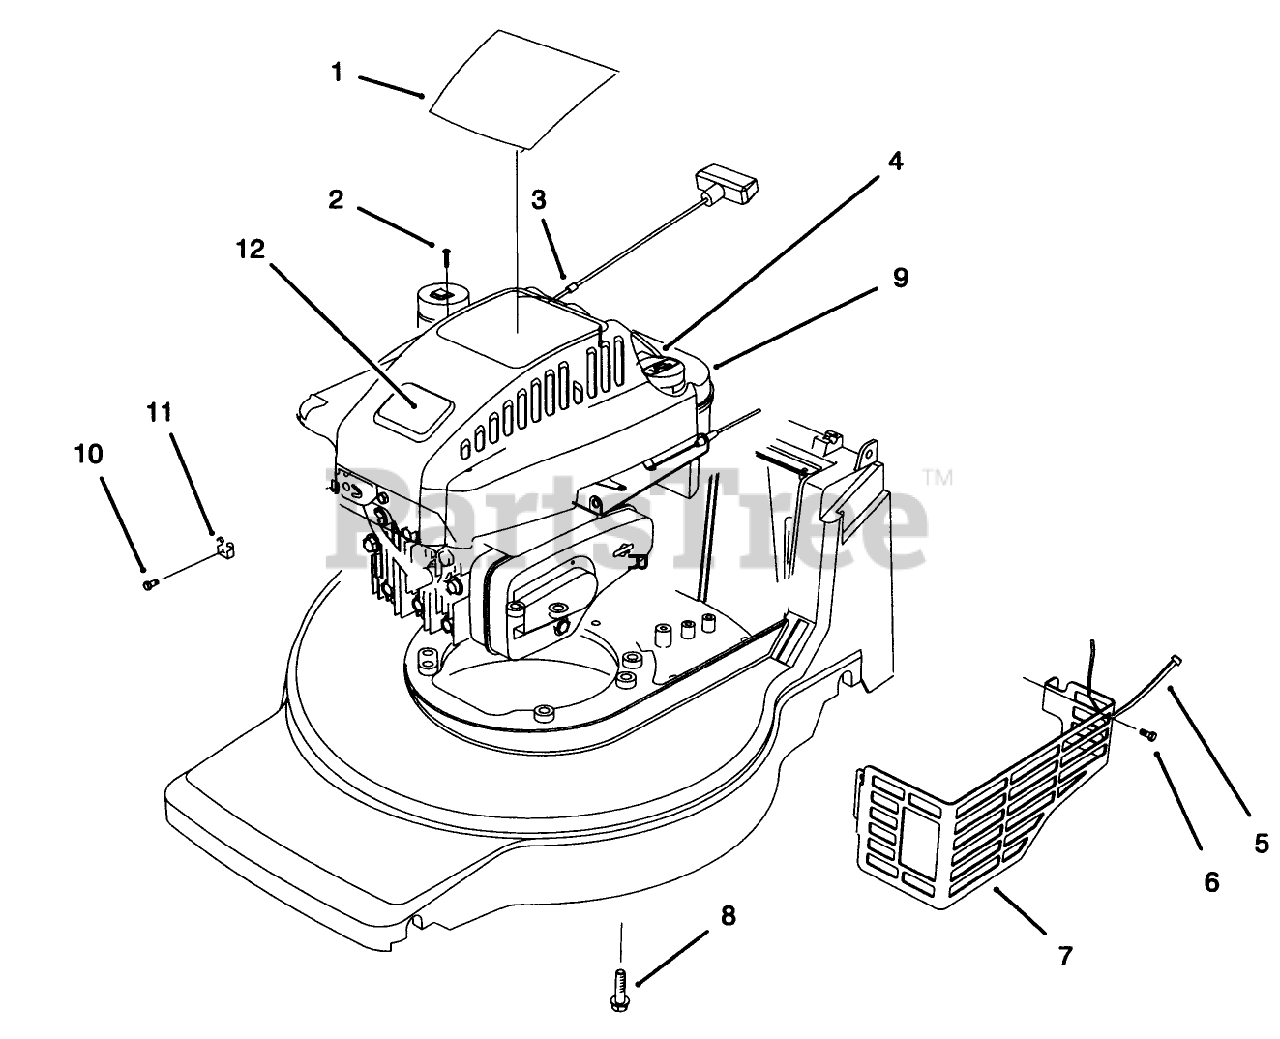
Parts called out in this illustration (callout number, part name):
1	DECAL - RECOIL
3	STOP-ROPE
4	SHROUD-ENGINE
5	TIE-CABLE
7	SHIELD - MUFFLER
8	SCREW-HWH
9	Engine-BS Quantum
10	SCREW-CLAMP
11	CLAMP-CASING
